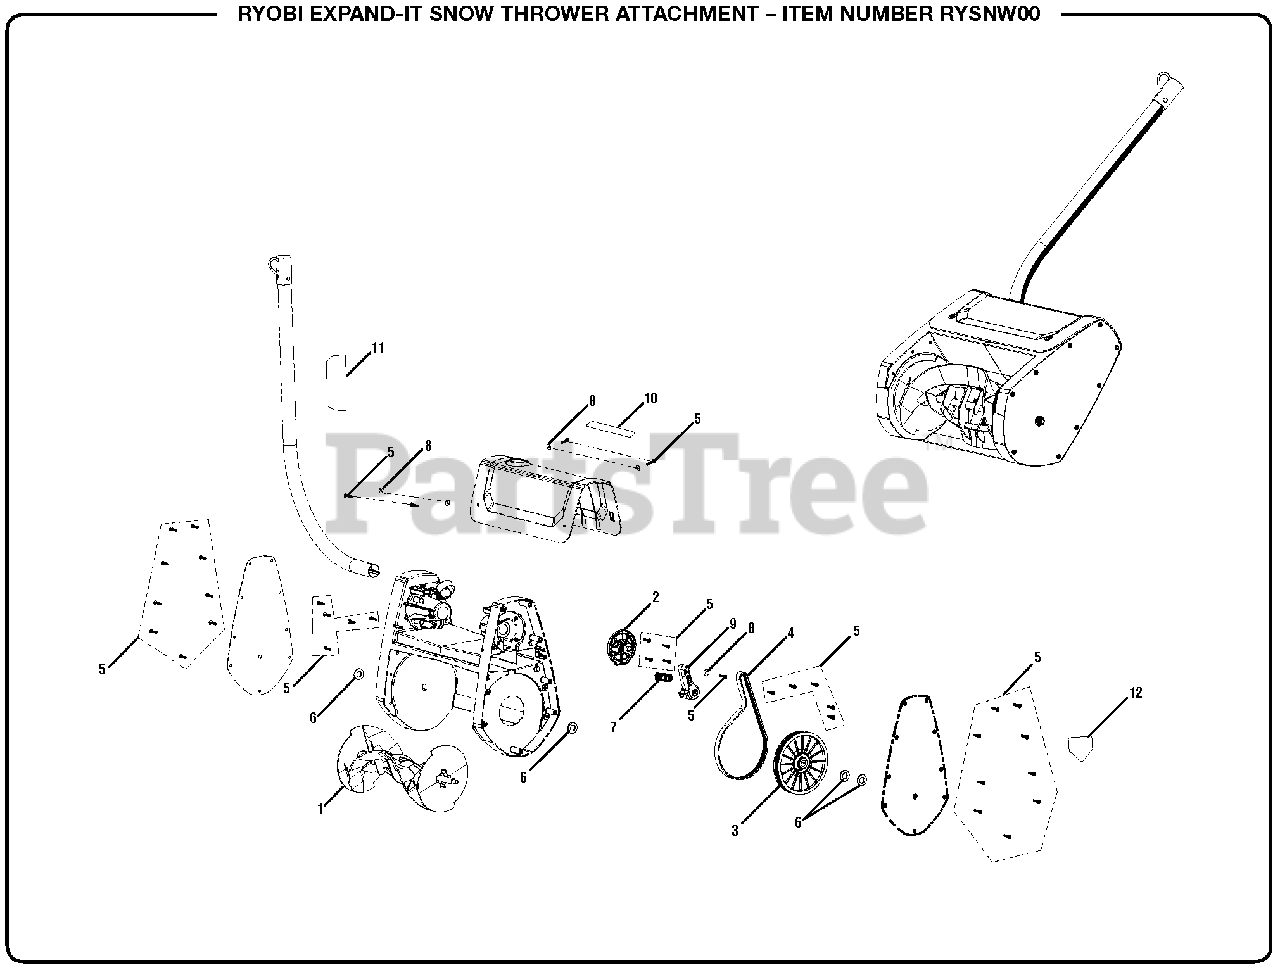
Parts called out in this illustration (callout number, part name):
1	Impeller w/Bushing
2	Bearing Housing Assembly
3	Pulley w/Bushing
4	Belt (V-Type, 590 mm)
5	Screw (M4 x 18 mm, T20 Torx Pan Hd.)
6	Washer (ID12.5 x OD24 x 2t)
7	Compression Spring
9	Tensioner Assembly
10	Icon and Warning Label
11	RYOBI Expand-IT Logo Label
12	No Hands/Feet Danger Label
